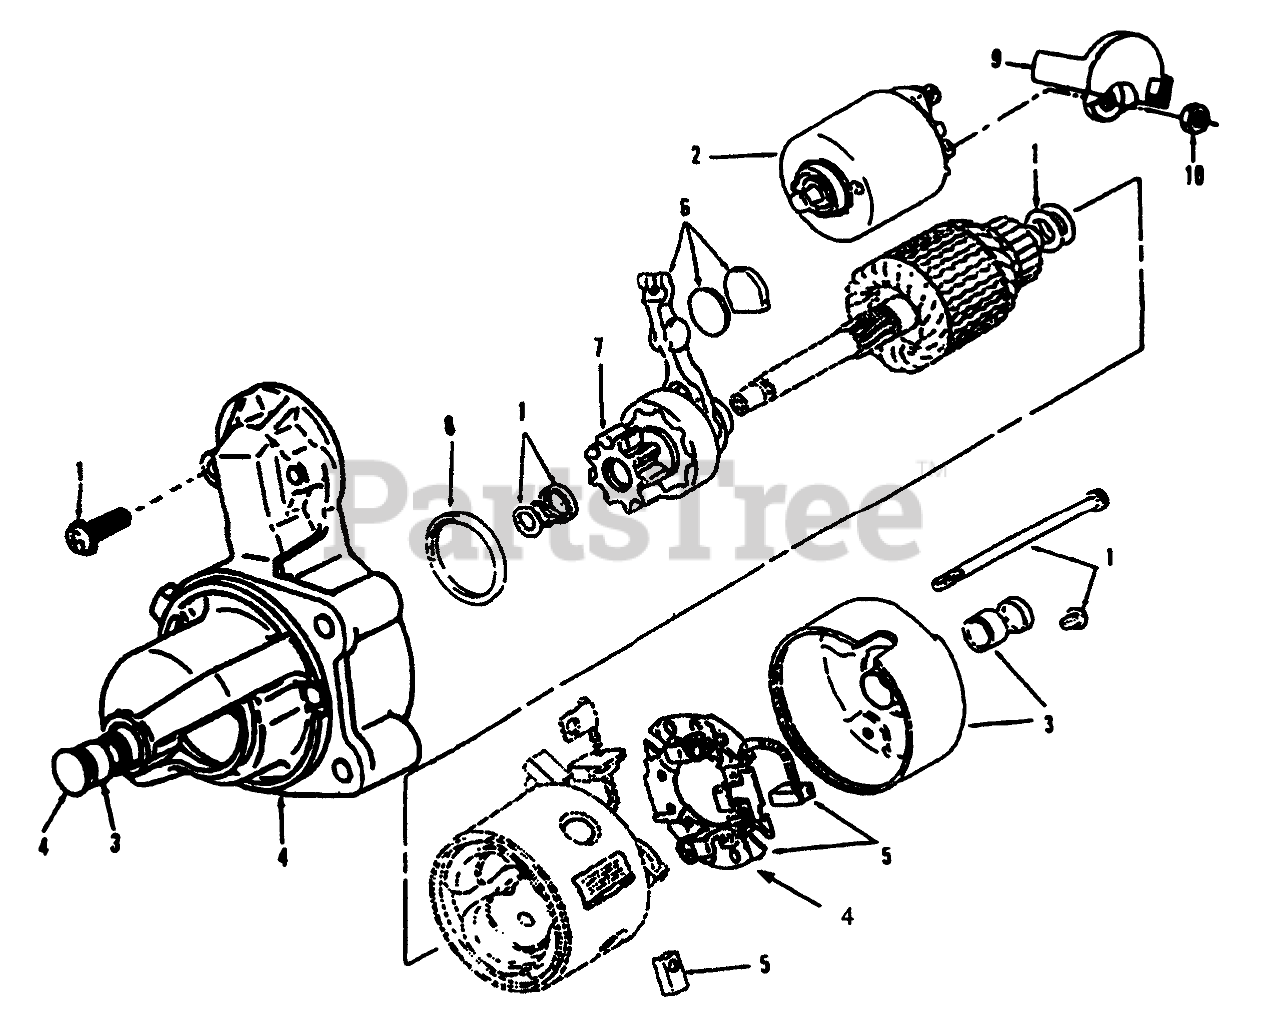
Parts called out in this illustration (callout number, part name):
1	Kit-Hardware, Starter (Includes (2) Solenoid Mtg Screws, 2 Thru Bolts, Armature Shims, Pinion Cdlar, & Retaining Ring)
2	Kit-Sdenid, Starter (Includes So bnoid & Spring Plunger)
3	Kit-Bushing, Starter (Includes Rear Cap with Bushing & Front Bushing)
4	KIT-MTG BRKT
5	Kit-Brush, Starter (Includes (2) Negative & (1) Positive Brushes)
6	Kit-Shift Lever, Starter (Includes Lever, Wear Plate & Rubber Plug)
7	Clutch Assembly-Starter (Includes Pinion Gear)
8	Dust Seal
9	Cap-Starter Solenoid
10	Nut-M8
